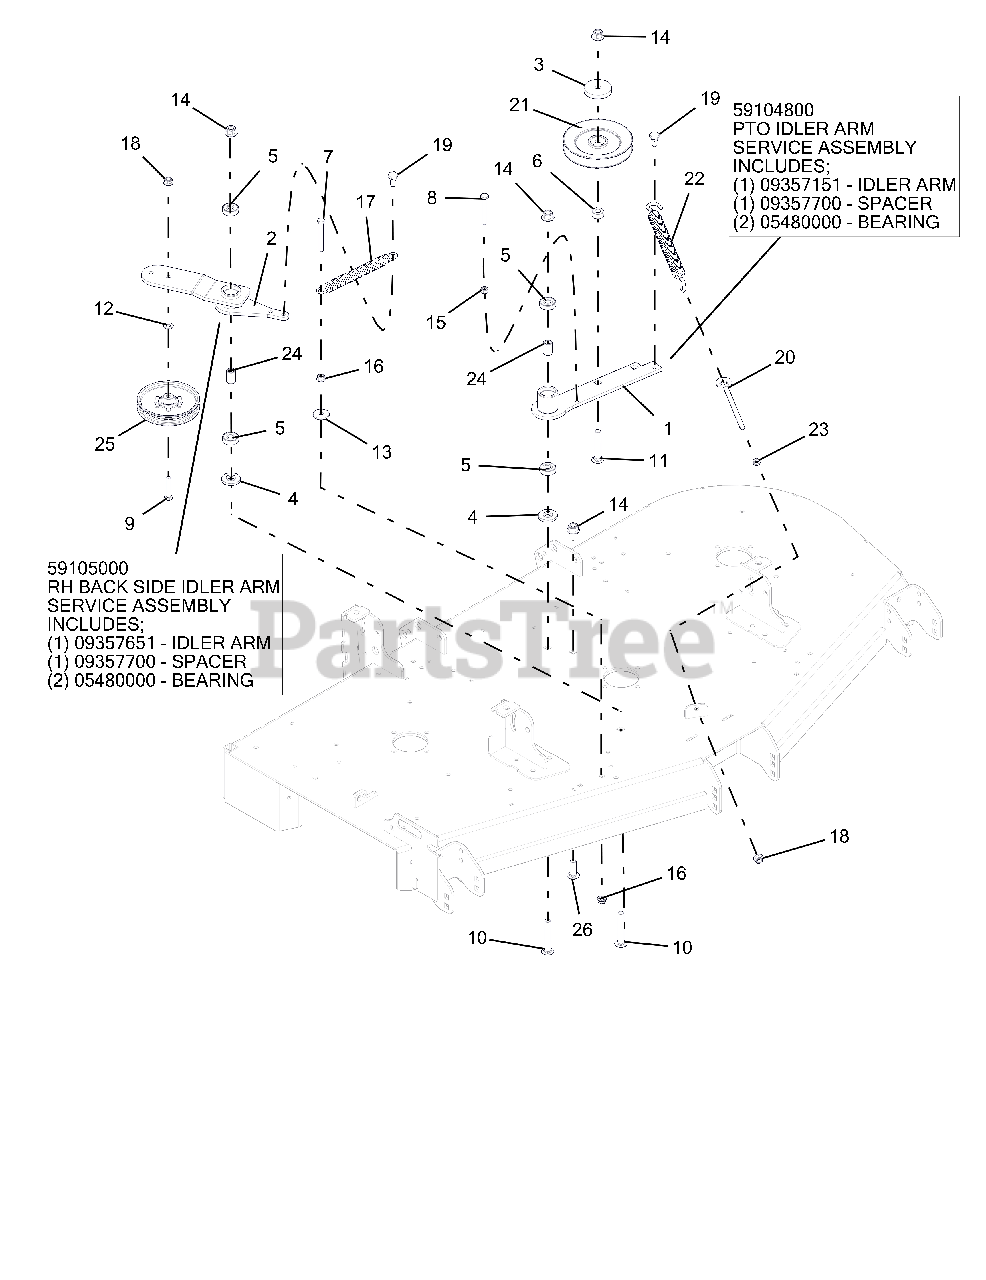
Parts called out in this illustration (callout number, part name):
1	WLDMT, DECK PTO IDLER ARM-BLACK
1	PTO IDLER ARM SERVICE ASSEMBLY
1	IDLER ARM
2	WLDMT, DECK RH IDLER ARM
2	RH BACK SIDE IDLER ARM SERVICE ASSEMBLY
2	IDLER ARM
3	CAP, IDLER BEARING SEALING
4	SPACER, IDLER ARM
5	BRG-BALL .500X1.375X.44
6	BSHG, SPCR .502 X .997.50 PM
7	BLT-HEX .38-16X3.00 GR5 YWZC
8	BLT-HEX .38-16X2.75 GR5 YWZC
9	BLT-HEX .38-16X2.00 GR5 YWZC
10	BLT-RDHDSQSHNK .50-13X3.25 YWZC
11	BLT-RDHDSQNK .50-13X3.00 G5 Y
12	WSHR-FL-STL.406X.812X.065 YWZ
13	WSHR-FL-STL .406X1.375X.135 YZ
14	NUT-LK-NYL-FLG .50-13 YWZC
15	NUT-HEX .38-16 YWZC
16	@NUT-SPNLK-FLG .375-16 YWZC
17	SPRG, EXTENSION .120X.845X6.55 WLD
18	NUT-LK-NYL-FLG .38-16 YWZC
19	BLT, SHLDR EP .38-16X.30 HEX YZ
20	BOLT, .38-16X6.00 .62 DIA EYE
21	SHEAVE, .50" ID X 6.00" OD V-IDLER
22	SPRG, EXTENSION
23	NUT, JAM .375-16 YWZC
24	SPACER, .510 X .750 X 1.148
25	PULLEY, FLAT IDLER .500 X .375 W/BRG
26	BLT-RDHDSQSHNK .50-13X1.50 YWZC
